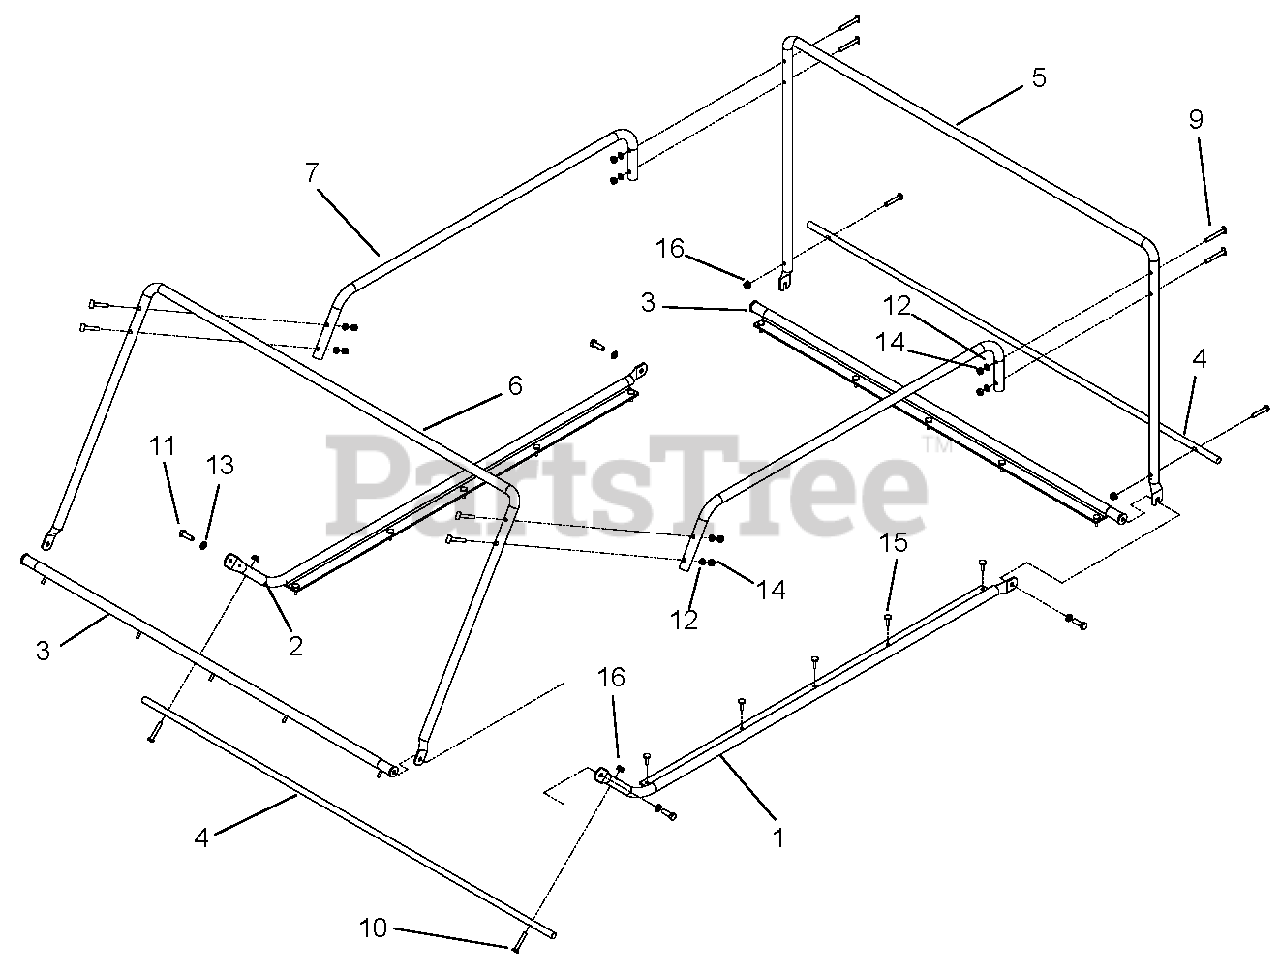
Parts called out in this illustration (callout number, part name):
1	Basket Clamp Assembly
2	Basket Clamp Assembly
3	Basket Clamp Assembly
4	Support Rod
5	Rear Upright
6	Front Upright
7	Frame Basket Side Top
9	Bolt, 1/4-20 x 2.0 Contour Head
10	Bolt, Hex 1/4-20 x 1.5 Grade 5
11	Bolt, Hex 5/16-18 x 1.00 Grade 5
12	Washer, Lock .25 x .062 YWZC
13	Washer, Lock .31 x .078 YWZC
14	Nut, Hex 1/4-20
15	Rivet, Bulb Tite
16	Nut, Nylock Flange .25-20
